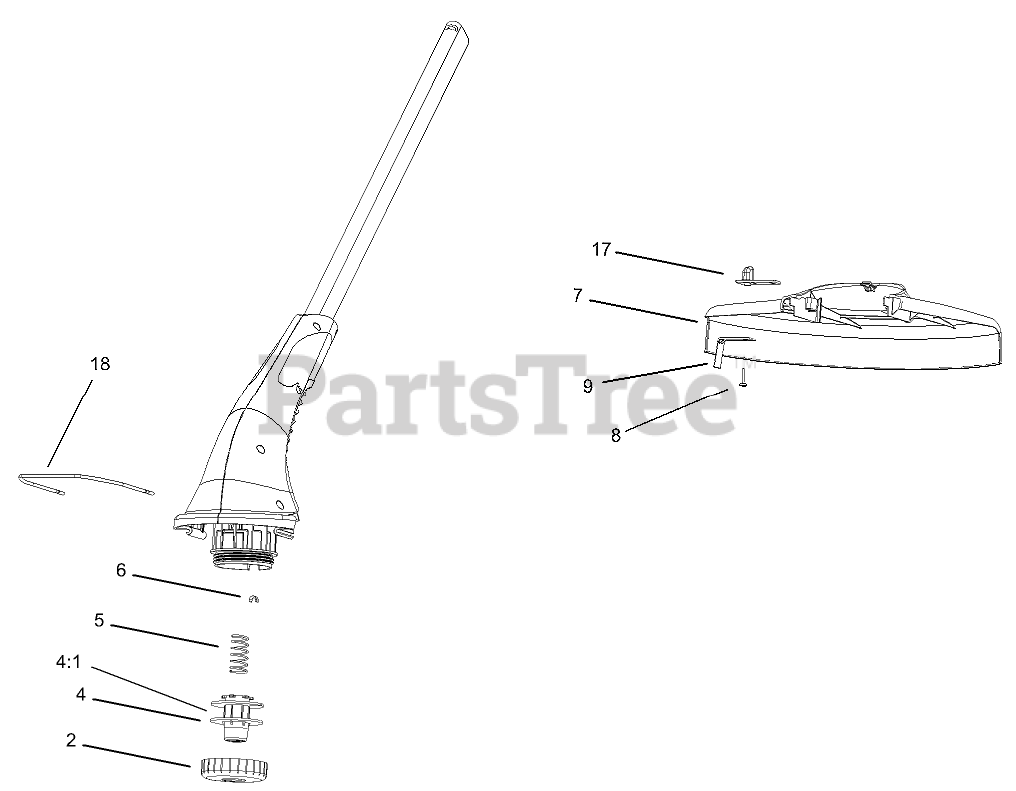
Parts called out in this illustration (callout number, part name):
2	Cap-Drum
4	.065 SPOOL ASM
4:1	SPOOL-LARGE
5	Spring-Extension
6	Eyelet-Drum
7	Shield-Variable Cut
8	SCREW-PPH
9	Blade-Variable Cut
17	Slide-Variable Cut
18	Guide-Edge
